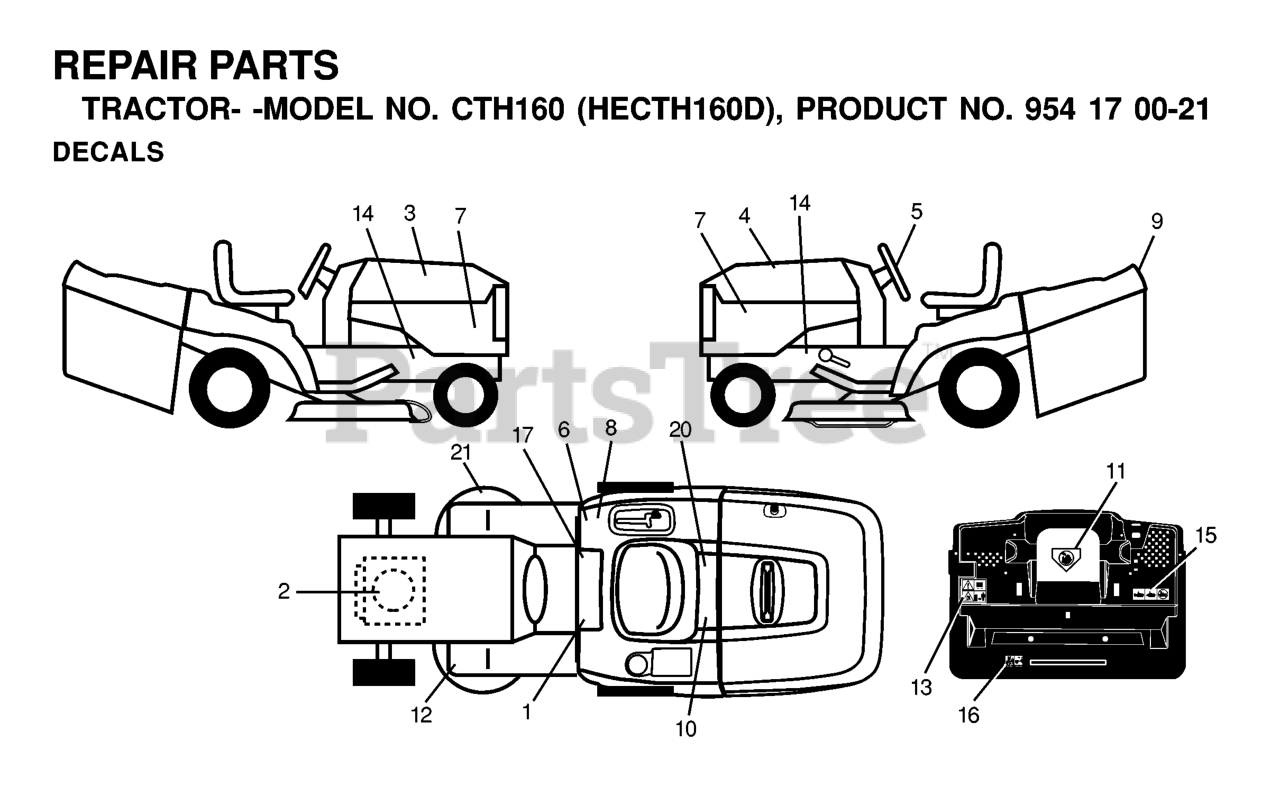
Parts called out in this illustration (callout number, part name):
1	DECAL READ OWNER'S MAN SYMS
5	DECAL.WHEEL.STEERING.HUSQ.PERM
6	DECAL CERTIFICATION
7	DECAL PNL SIDE
8	DECAL EUROPE STANDARD CE
9	DECAL FENDER HUSQ
10	DECAL BTRY SYMBOLS
11	DECAL MOWER CUT/FINGER
12	DECAL
13	Decal Warn Back Plate CRD
16	DECAL
17	DECAL PARK BRAKE
20	DECAL.BYPASS.FENDER.CRD.LT.YT
